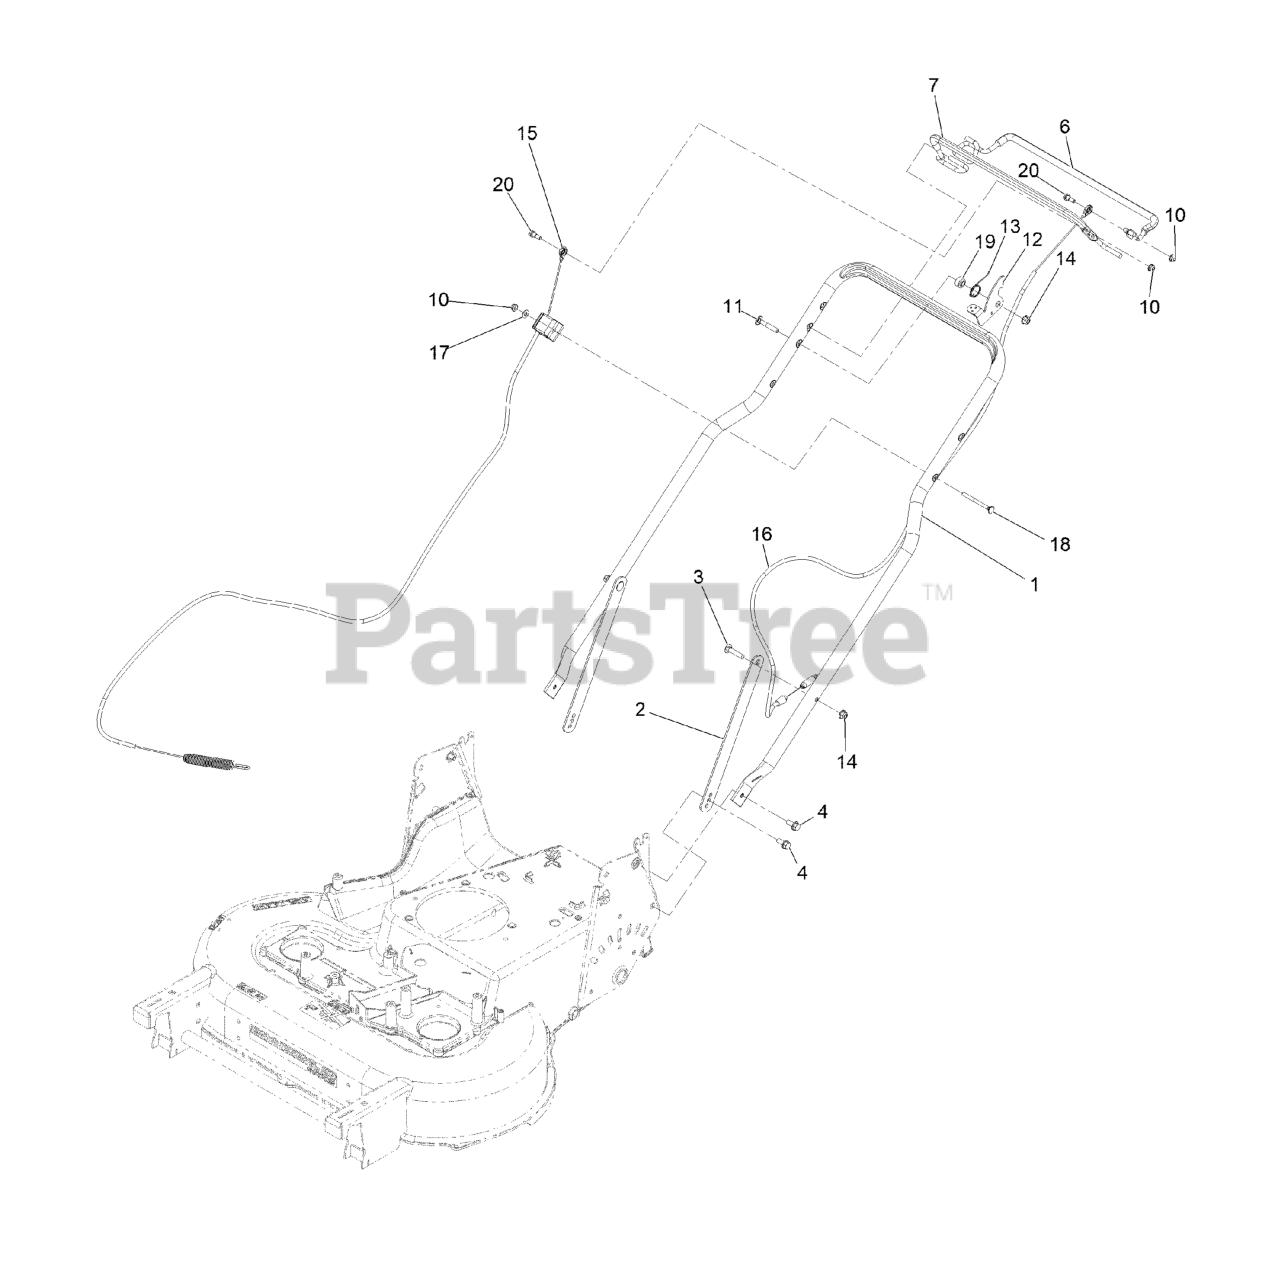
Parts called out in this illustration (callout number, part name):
2	SUPPORT-HANDLE
3	BOLT-CARR
4	SCREW-HHF
6	BAIL-TRACTION, COATED
7	BAIL-BBC, COATED
12	LEVER-BBC
13	SPRING-LEVER, BBC
14	NUT-HF, NI
15	CABLE-BBC
16	CABLE-TRACTION
17	Washer-Flat
18	Screw-Handle
19	BUSHING-STEPPED
20	BOLT-SHOULDER
